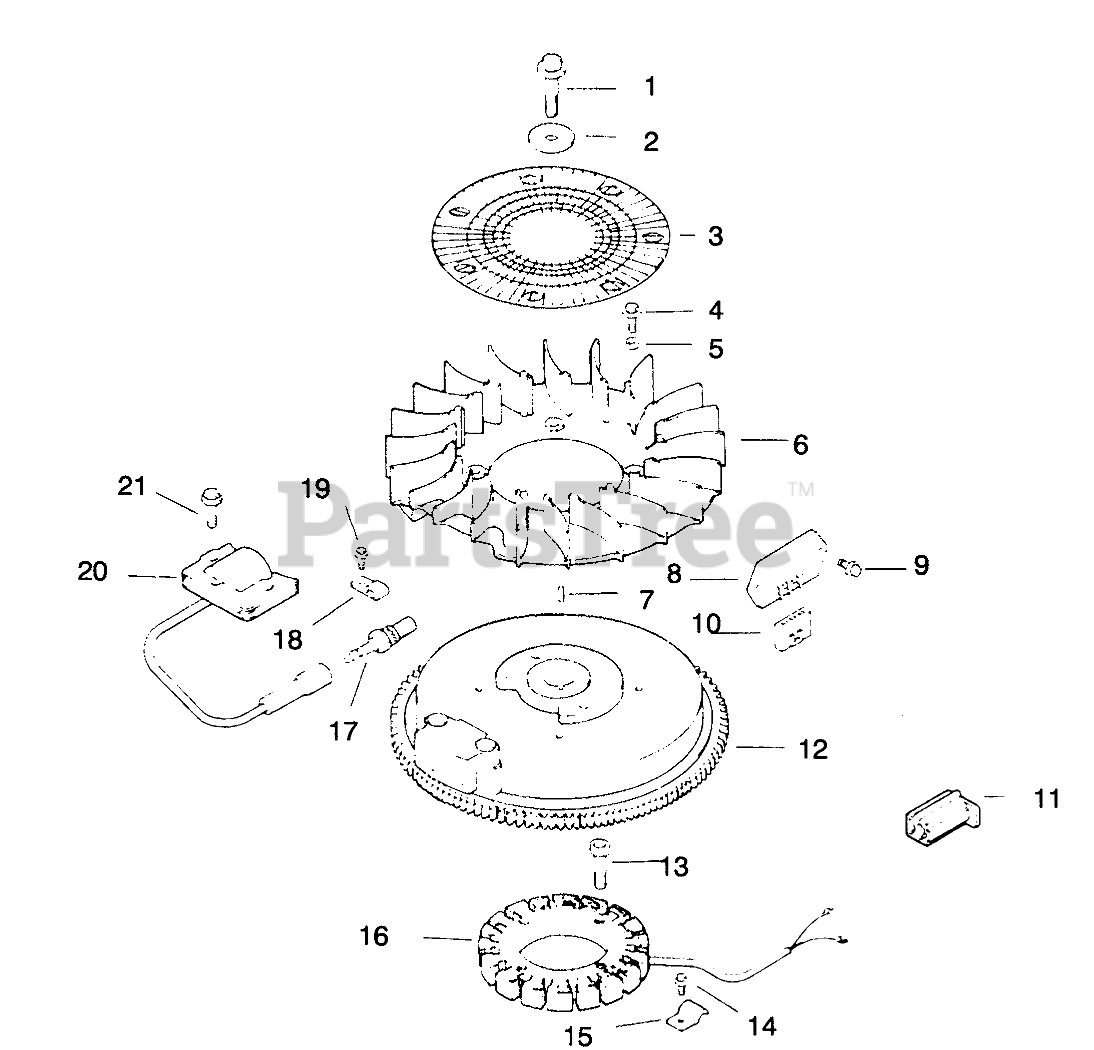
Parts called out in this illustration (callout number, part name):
1	Screw
2	Washer-Flat
3	Screen-Grass
4	Screw
5	Spacer-Fan
6	Fan
7	Key
8	Rectifier-Unregulated
9	Screw
10	Connector
11	Connector
12	Flywheel ASM
13	Screw
14	Screw
15	Clip-Stator Harness
16	Stator-15 Amp
17	Plug-Spark
18	Clip
19	Screw
20	Module-Ignition
21	Screw
